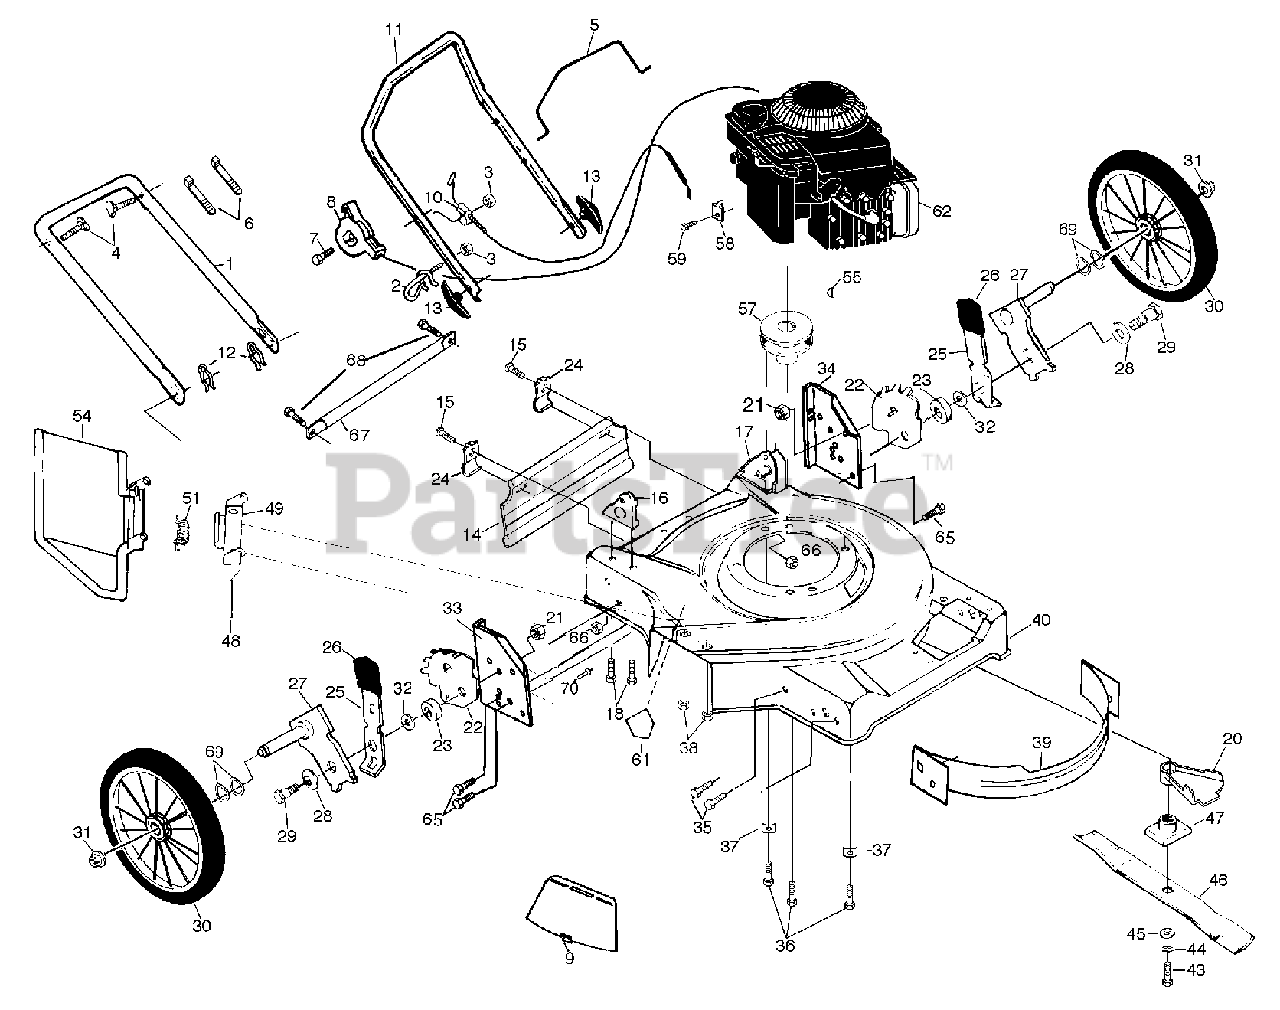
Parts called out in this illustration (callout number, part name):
2	Drive Control
3	Locknut #10-24
4	Hex Washer Head Screw 1/4-20 x 2.12
6	Spring Retainer
8	Hubcap
9	Flanged Locknut 3/8-16
11	Wheel & Tire Assembly
12	E-Ring
13	Pinion
14	Dust Cover
16	Washer 1/2 x 1-1/2 x .134
18	Selector Knob
19	Hex Locknut 1/4-20
22	Wire Tie
26	Pan Head Tapping Screw #10-24 x 2-3/4
27	Hex Head Tapping Screw #10-2
28	Drive Cover
31	Hex Flange Nut
32	Drive Pulley
35	Wheel Adjuster Assembly (Left)
36	Gear Case Assembly
37	Spring
40	Spring
41	Wheel Adjuster Assembly (Right)
55	Driveshaft Cover
